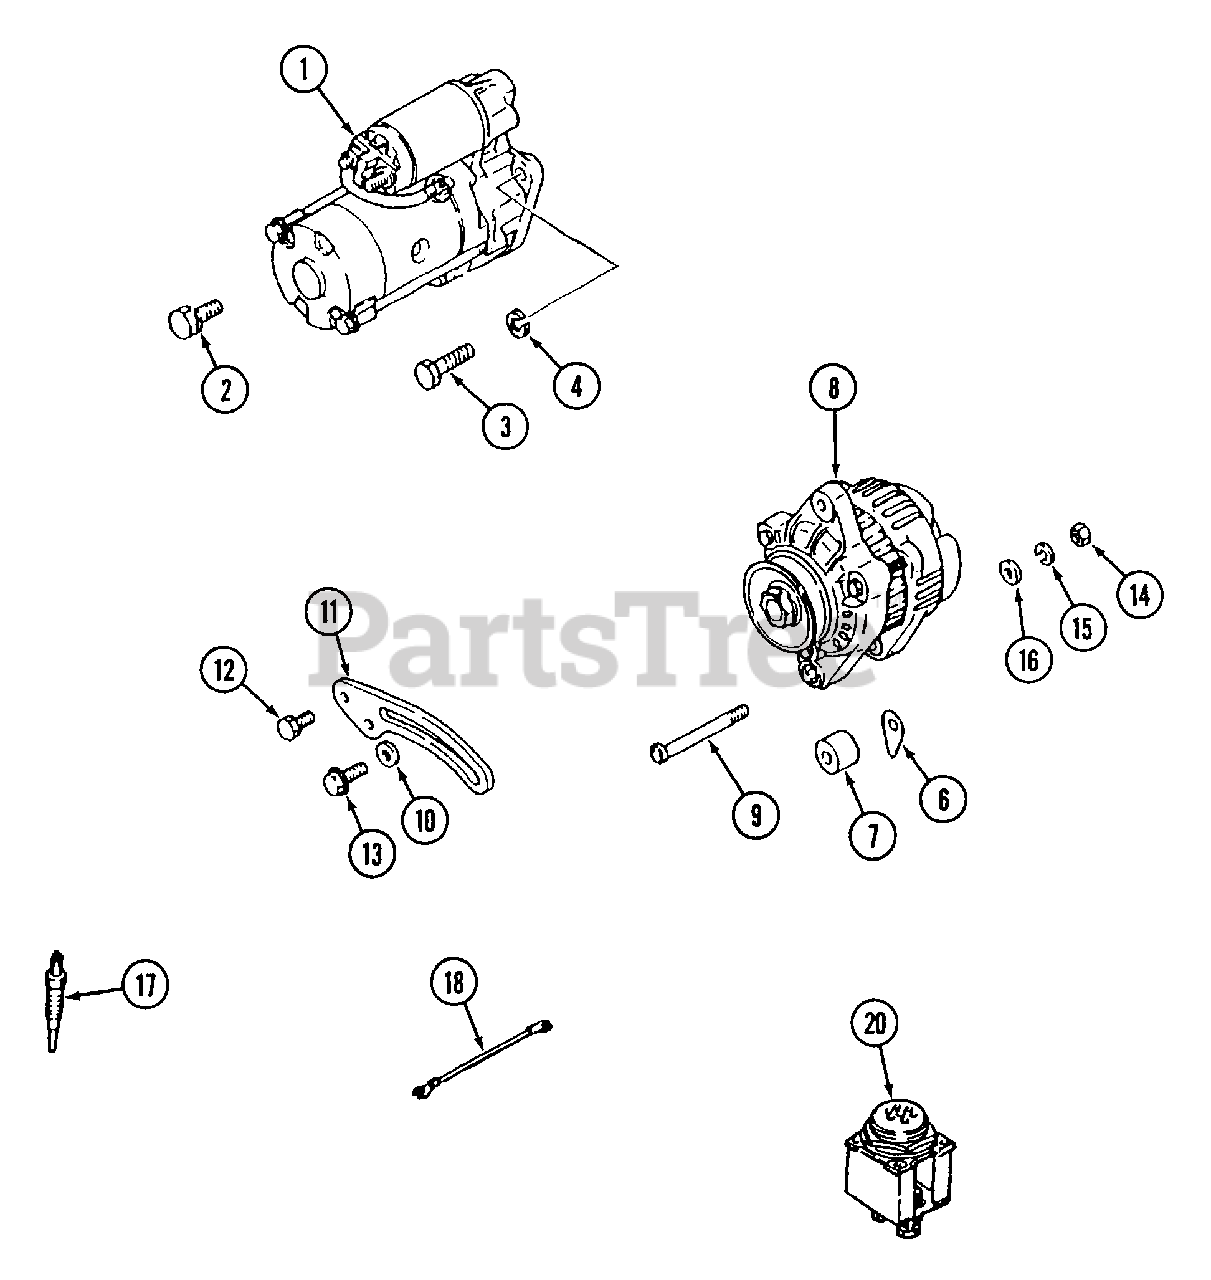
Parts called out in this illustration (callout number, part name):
1	Starter Ass'y.
2	Bolt,
3	Bolt, Starter
4	Washer, Lock
8	Alternator Ass'y.
9	Bolt, Special
10	Washer, Plain
11	Blace, Generator
12	Bolt,
13	Bolt, Flange
15	Washer, Spring
16	Washer, Plain
17	Plug, Glow
18	Wire, Glow Plug Lead
20	Lamp, Glow
